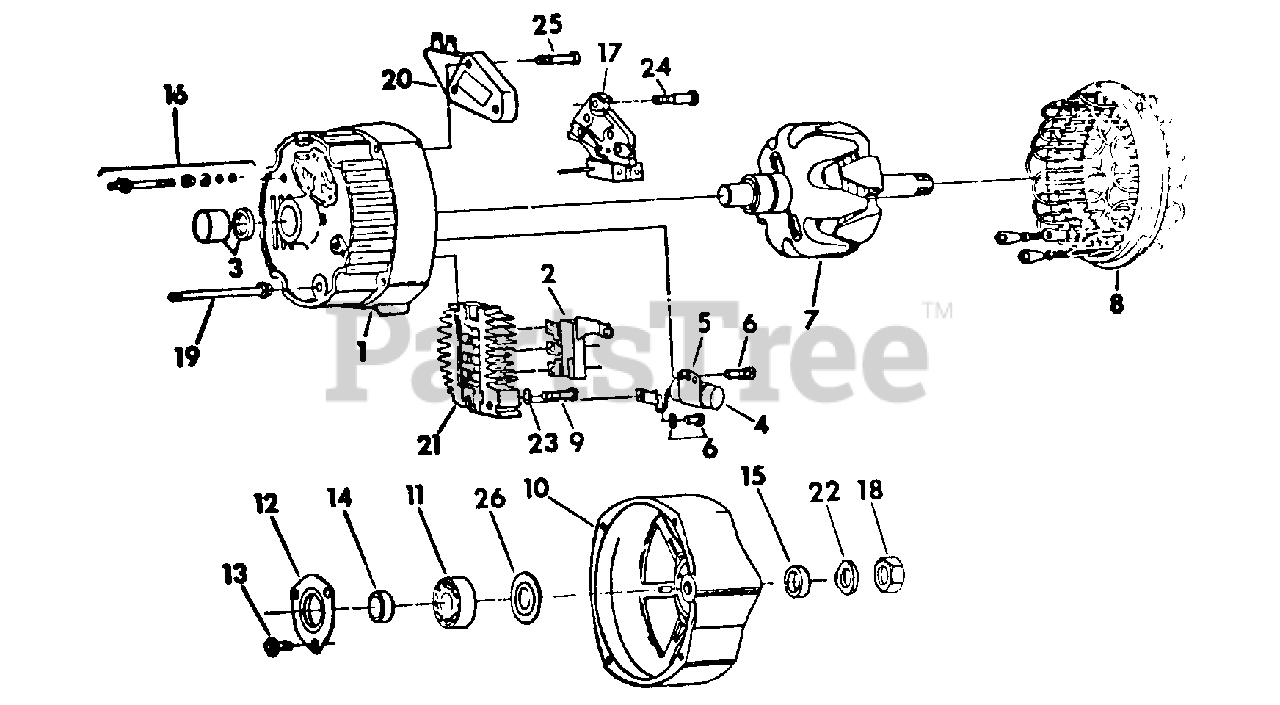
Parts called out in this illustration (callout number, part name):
1	FRAME, SLIP RING END
2	DIODE TRIO, NEGATIVE
3	BEARING, SLIP RING END
5	BRACKET, CAPACITOR ATTACHING
6	SCREW, CAPACITOR BRACKET
7	ROTOR ASSY
8	STATOR ASSY
9	SCREW, RECTIFIER BRIDGE ATTACHING
10	PACKAGE, DRIVE END FRAME
11	BEARING, DRIVE END BALL
12	PLATE, DRIVE END BALL BEARING RETAINER 1
13	SCREW, RETAINER PLATE ATTACHING
14	COLLAR, INSIDE DRIVE END
15	COLLAR, DRIVE END SHAFT - OUTSIDE 1 IN. OD
15	COLLAR, DRIVE END SHAFT - OUTSIDE
16	PACKAGE, BATTERY OUTPUT TERMINAL
17	BRUSH HOLDER & BRUSH ASSY
18	NUT, DRIVE END SHAFT
20	REGULATOR, VOLTAGE SOLID STATE
21	BRIDGE, POSITIVE RECTIFIER
22	WASHER, DRIVE END SHAFT NUT LOCK
23	WASHER, RECTIFIER BRIDGE NUT SPRING SCREW SPRING
24	SCREW, INSULATED BRUSH HOLDER
25	SCREW, GROUND BRUSH HOLDER
26	WASHER, DRIVE END GREASE SLINGER
